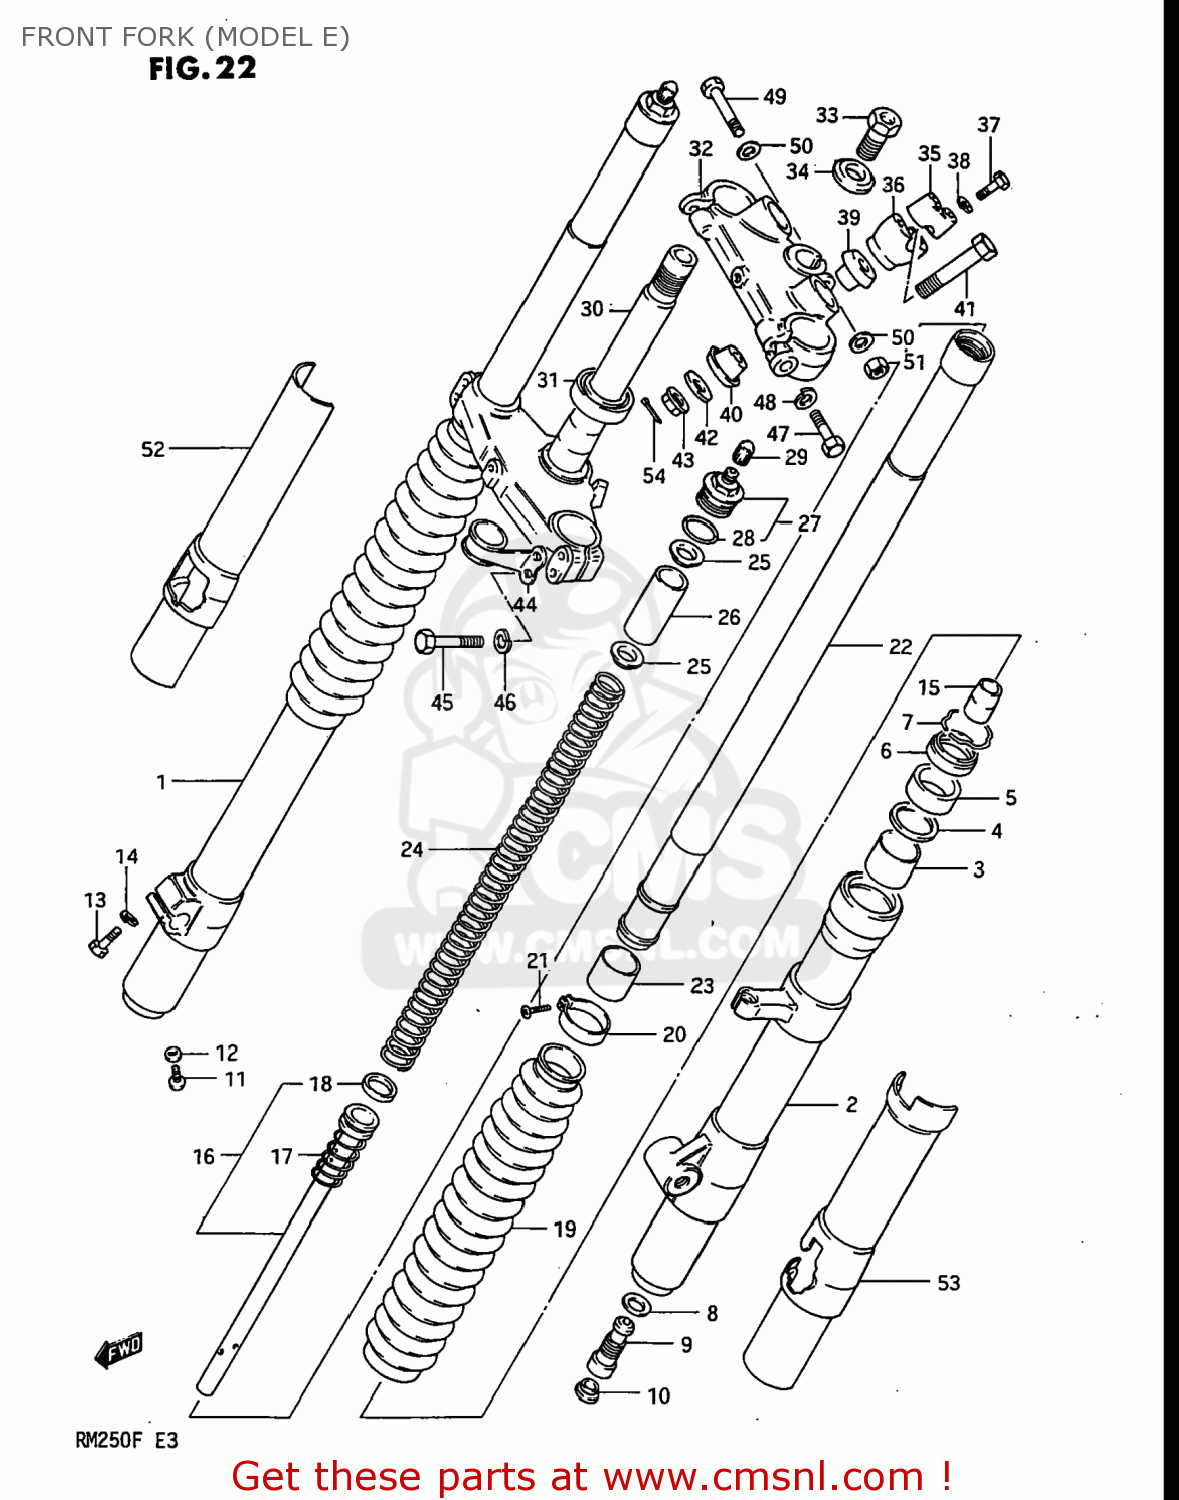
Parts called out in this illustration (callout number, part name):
1	TUBE,OUTER,RIGHT
2	TUBE,OUTER,LEFT
3	METAL,SLIDE
4	WASHER
5	SEAL,OIL
6	SEAL,DUST
7	RING,STOPPER
8	GASKET,FORK CYLINDER
9	VALVE,DF
10	CAP,FRONT FORK DF
11	SCREW 4X6
12	GASKET,DRAIN,PLUG (NAS)
13	BOLT (8X30)
14	WASHER,LOCK,8.
15	PIECE,FRONT FORK OIL LOCK
16	CYLINDER,FRONT FORK
17	SPRING,REBOUND
18	RING,FRONT FORK PISTON
19	BOOT,FRONT FORK COVER
20	BAND,BOOT,UPPER
21	SCREW 4X10
22	TUBE,FORK,INNER
23	PISTON
24	SPRING,FRONT FORK
25	GUIDE,FRONT FORK SPRING
26	SPACER,FRONT FORK SPRING
27	CAP,FORK INNER TUBE
28	O RING
29	CAP
30	STEM,STEERING
31	BEARING
32	HEAD,STEERING STEM
33	BOLT
34	WASHER
35	HOLDER,HANDLEBAR
36	HOLDER,HANDLE LWR
37	BOLT
38	WASHER,LOCK,8.
39	DAMPER,UPR
40	DAMPER,LWR
41	BOLT,HANDLE HOLDER
42	WASHER,HANDLEBAR HOLDER
43	NUT
44	GUIDE,CABLE
45	BOLT 8X40
46	WASHER,LOCK,8.
47	BOLT
48	LOCK WASHER
49	BOLT 8X50
50	WASHER
51	NUT
52	PROTECTOR,RIGHT
53	PROTECTOR
54	PIN 20X20
